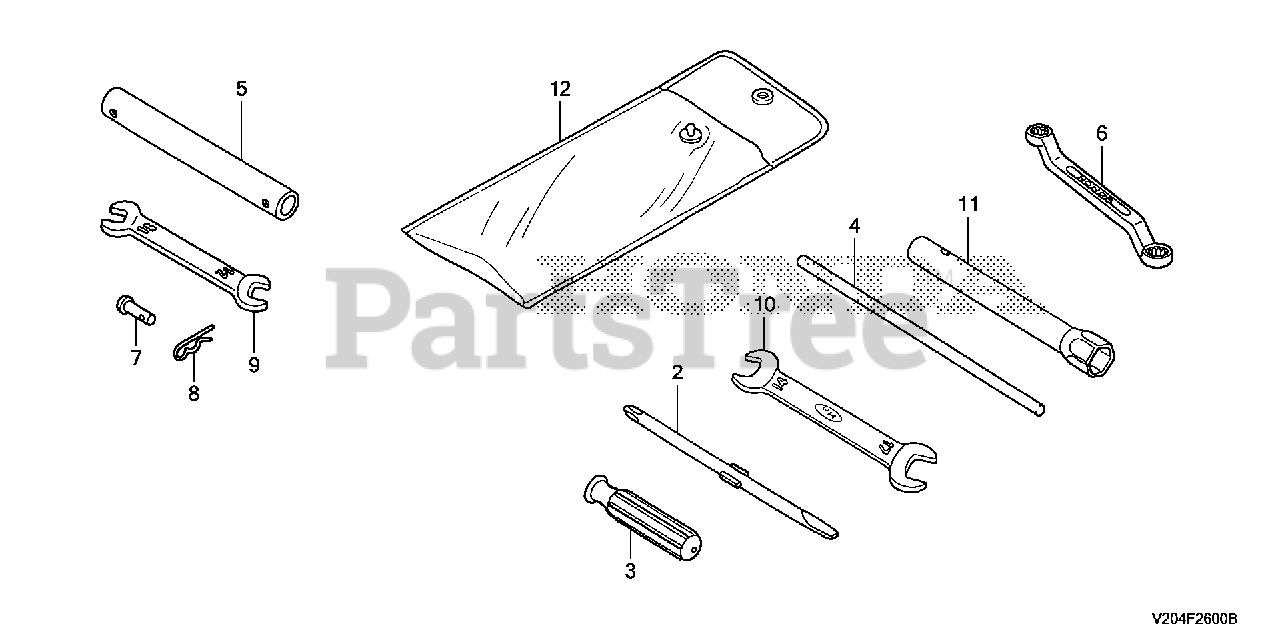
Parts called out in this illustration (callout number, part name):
2	SCREWDRIVER (NO.2 PHILLIPS -)
3	GRIP
4	HANDLE, BOX WRENCH (NOT AVAILABLE)
5	PIPE, BOX WRENCH EXTENSION
6	WRENCH, EYE (10X12)
7	PIN, ROLLER ARM (8X22)
8	PIN, LOCK (8MM)
9	WRENCH (10X12) (OPEN END)
10	WRENCH (14X17) (OPEN END)
11	WRENCH, BOX (P21)
12	BAG, TOOL (230MM)
